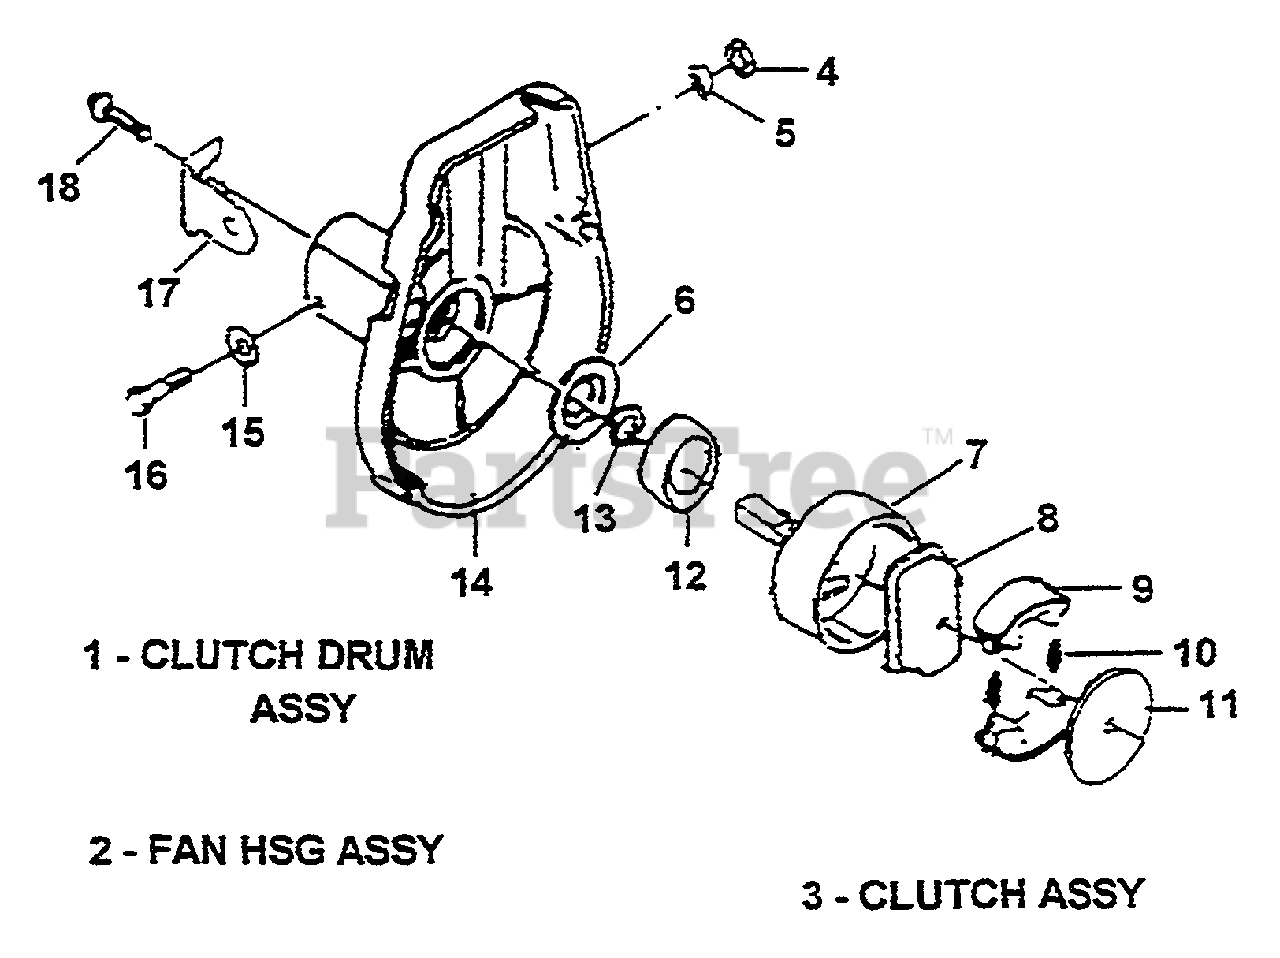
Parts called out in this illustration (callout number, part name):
1	CLUTCH DRUM ASSY
2	FAN HOUSING ASSY
3	CLUTCH ASSY
6	THRUST WASHER
7	DRUM, CLUTCH
8	ROTOR, CLUTCH
9	SHOE, CLUTCH
10	SPRING, CLUTCH
11	PLATE, WASHER
13	RETAINING RING
14	HOUSING, FAN
